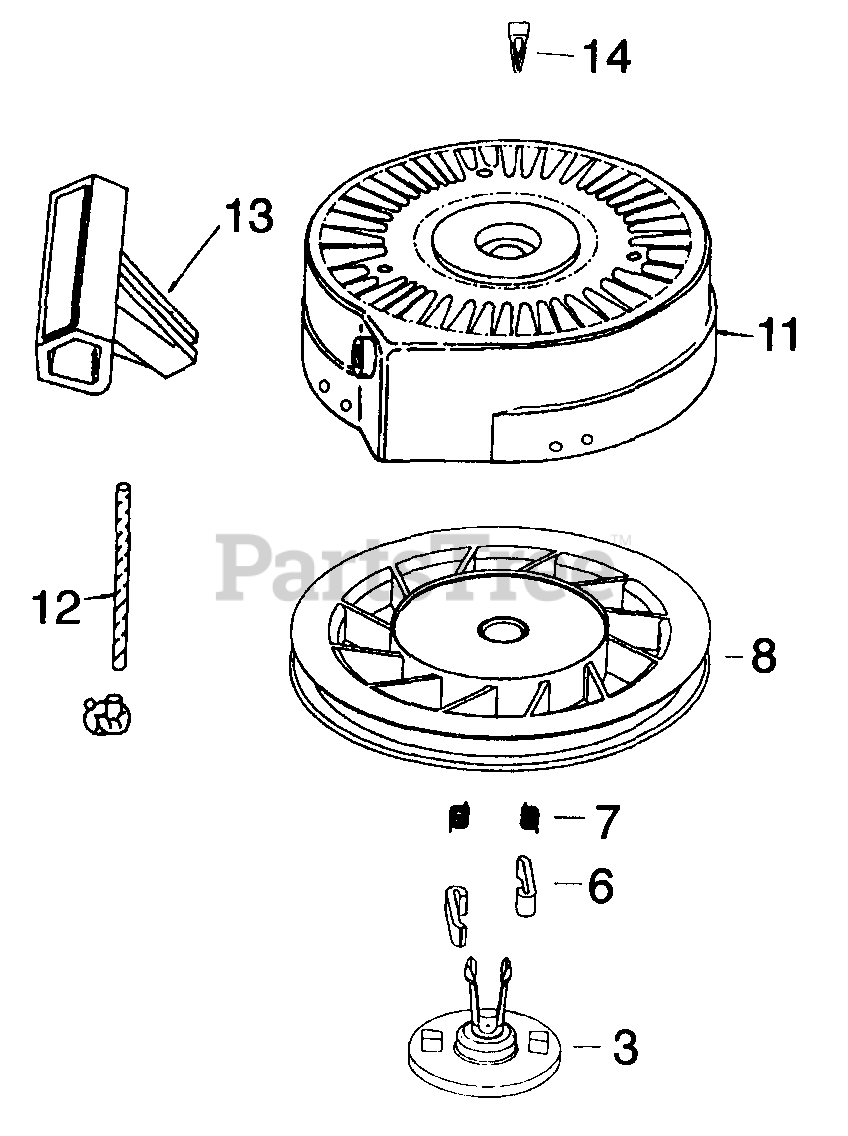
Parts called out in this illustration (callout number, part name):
6	Starter Dog
7	Dog Spring
8	Pulley & Rewind Spring Assy
11	Starter Housing Assy
12	Starter Rope
13	Starter Handle
14	Locking Tab
